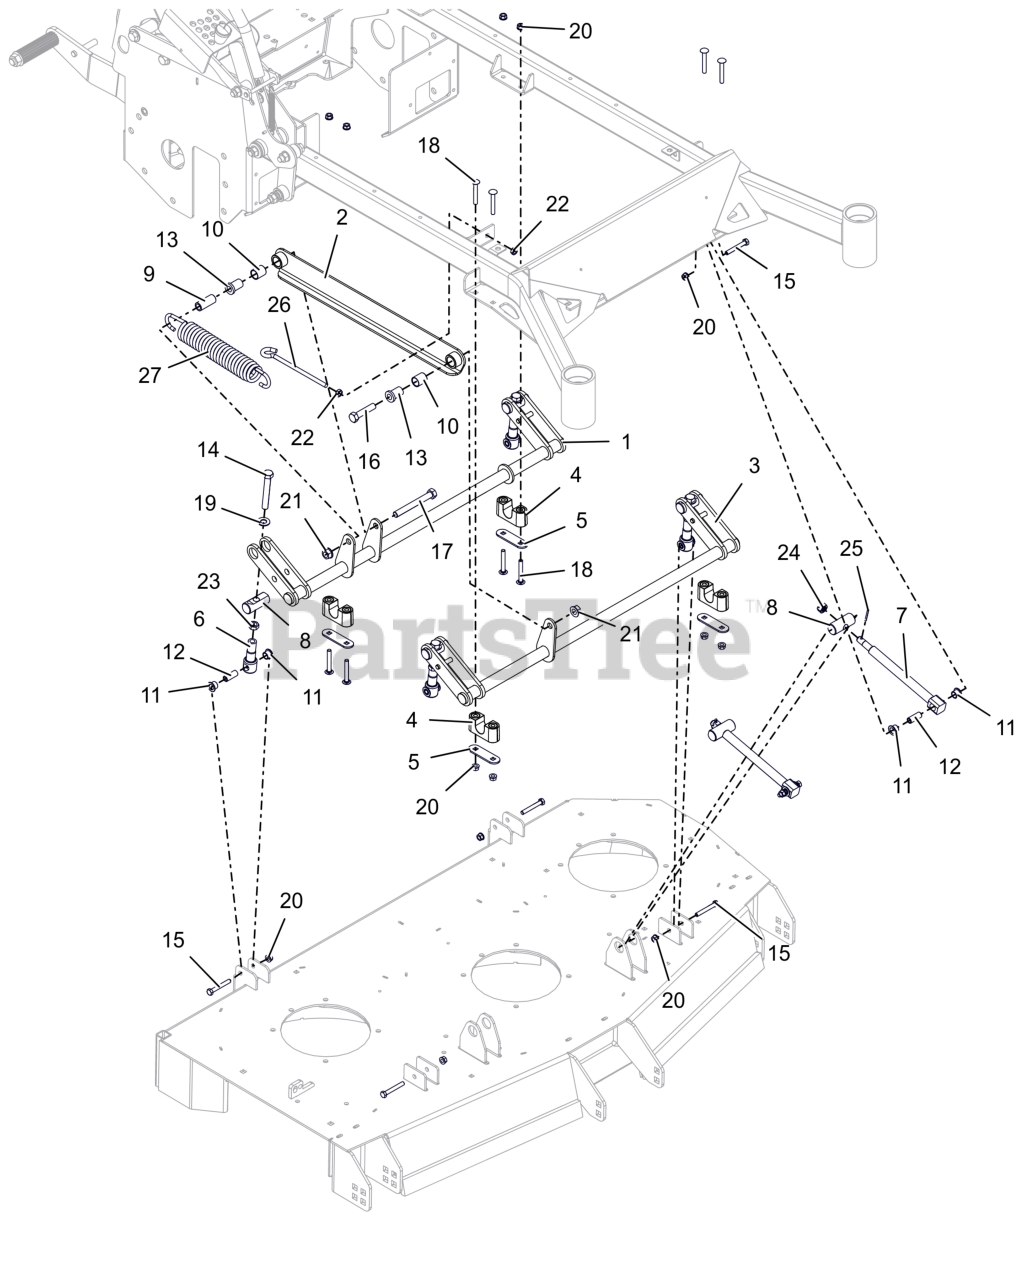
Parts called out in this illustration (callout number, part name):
1	WLDMT- DECK LIFT
2	LINK- DECK LIFT (BLACK)
3	WLDMT- DECK LIFT - FRONT
4	ASM-BUSHING, DECK LIFT
5	PLATE, BEARING SUPPORT
6	LINK, DECK LIFT FORMED
7	DRAG,LINK-HD
8	PIN, DECK LIFT
9	BUSHING- .515 X 1.000 X 3.088
10	BRG- .750 X .875 X 1.000
11	BSHG, FLANGED .50X.625X.50X.062
12	SPCR, .31X.50X1.265
13	BSHG-FLG .515X.746X1.290X1.000
14	BLT, HEX .50-13X3.50F G5 ZCC
15	BLT, HEX .31-18X2.25 G5 ZCC
16	BLT, HEX .50-13X2.25 G5 ZCC
17	BLT, HEX .50-13X4.25 G5 ZCC
18	BLT, RHSSN.31-18X2.25 G5 ZCC
19	WSHR, FLT .557X1.040X.102 ZCC
20	NUT,LK-CTR-FLG .31-18 GF ZCC
21	NUT-LK-CTR-FLG .500-13 GG ZCC
22	NUT-JAM .375-16 G2 ZCC
23	NUT-JAM .500-13 G2 ZCC
24	NUT-SL .50-13
25	PIN,CTR.12X1.25EXTPRSQCT ZC120
26	BOLT, .38-16X6.00 .62 DIA EYE
27	SPRG-EXTEN - .273X1.853X10.125
